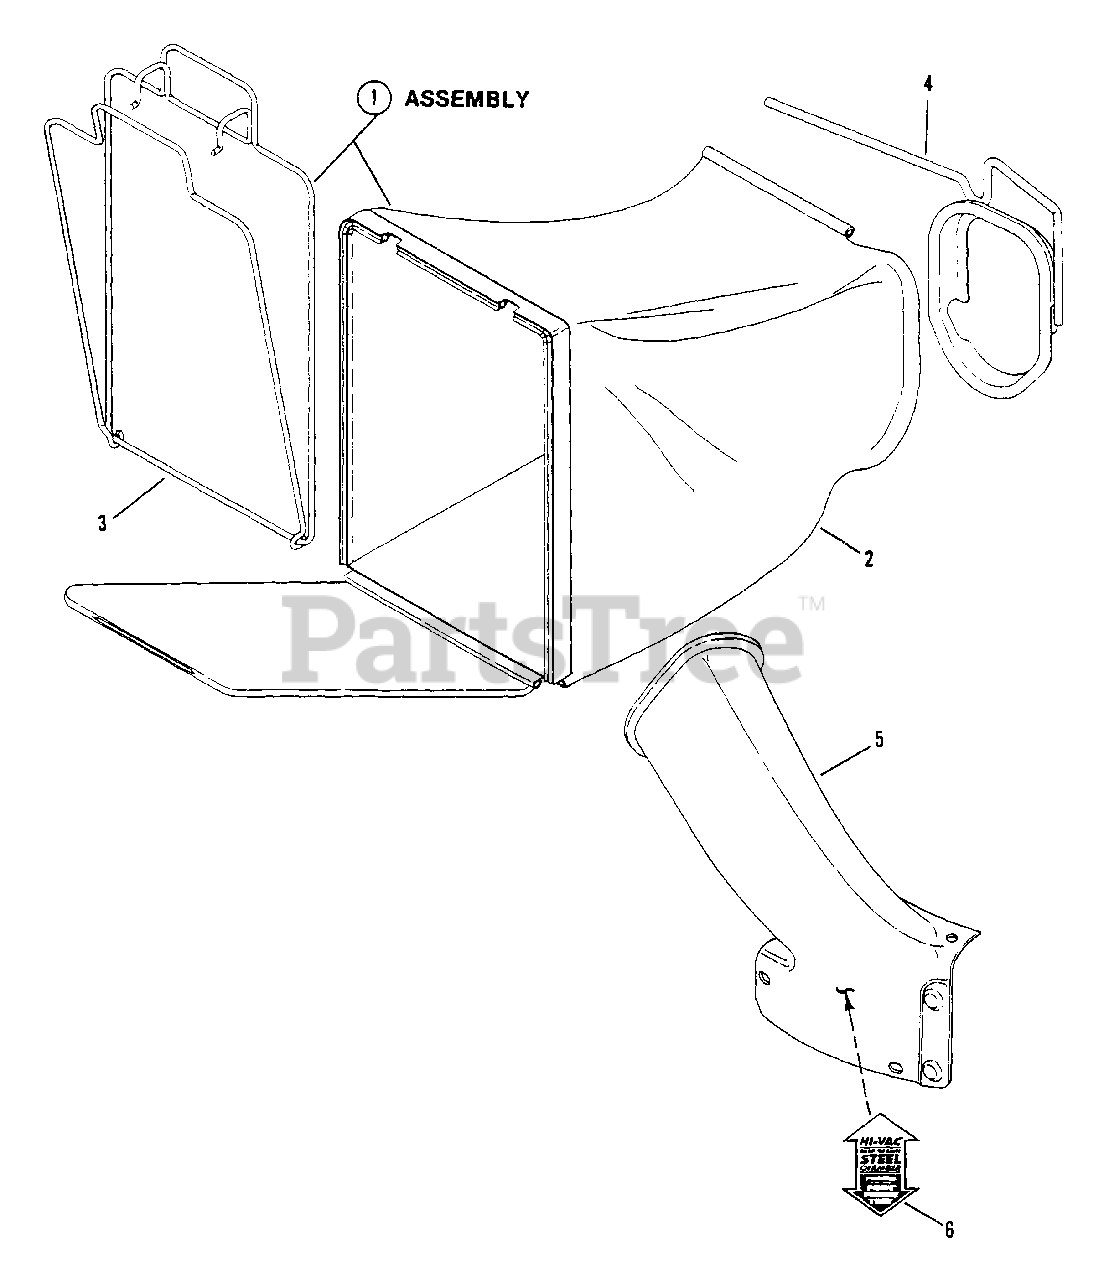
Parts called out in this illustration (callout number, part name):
1	ASSEMBLY, Grass Bag (Door Type)
2	BAG, KWIK-N-EZY
3	ASSEMBLY, Bag Wire
4	CONNECTOR, Grass Bag
5	ADAPTER, Bag
6	DECAL, Hi-Vac/Foot Probe (Red)
